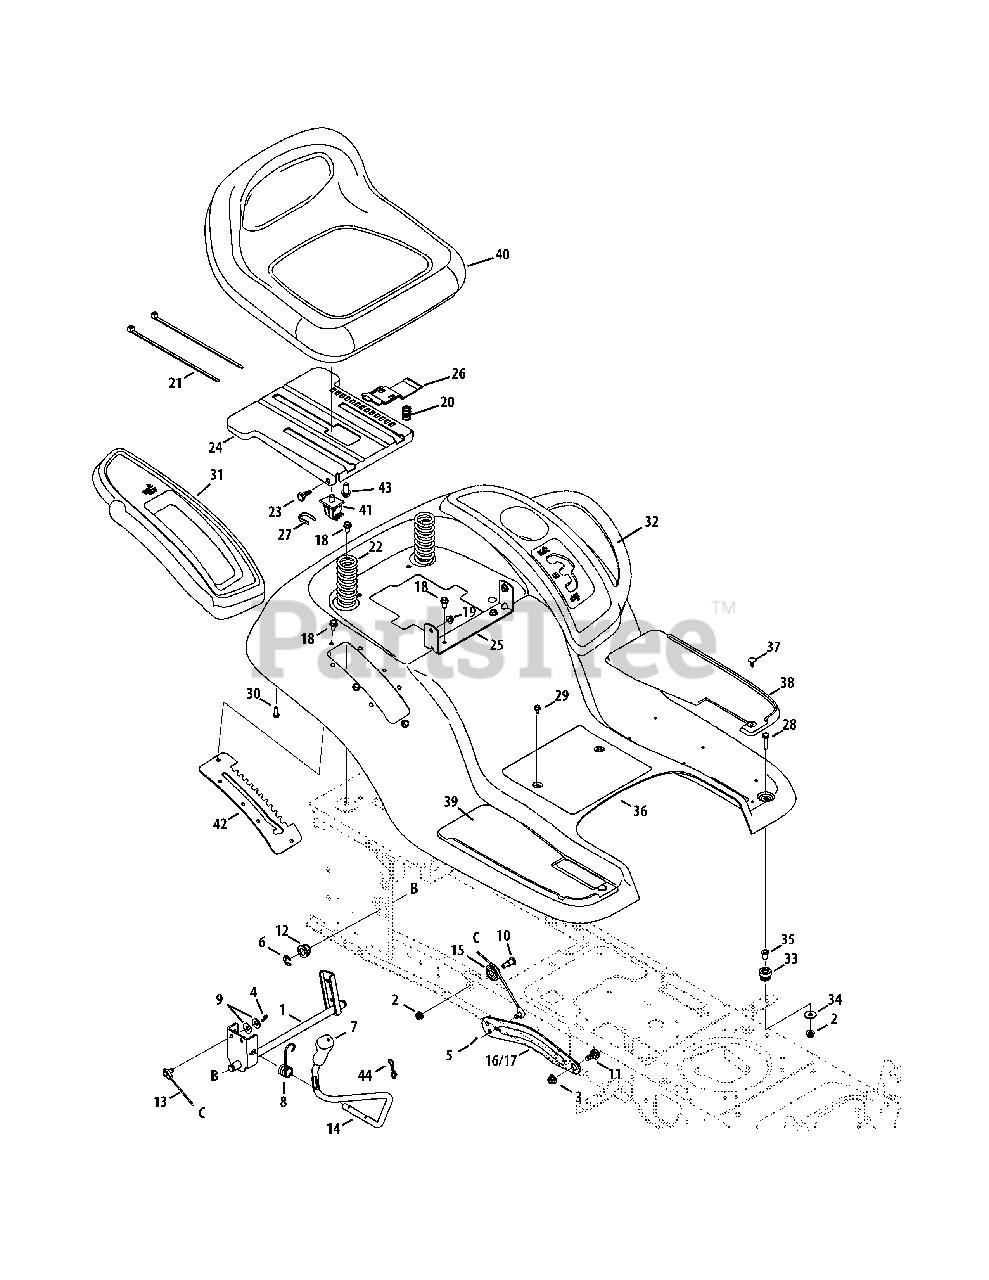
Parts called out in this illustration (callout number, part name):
1	Shaft Asm, Lift
2	Nut, Flange Lock, 5/16-18, Grf
3	Nut, Flange Lock, 3/8-16, Grf
4	Pin, Cotter, .072 Dia. x 1.13
5	Pin, Cotter, Bow-Tie 72
6	Ring, E Type, .625 Dia. Shaft
7	Grip, Handle, Cub, .50 ID
8	Spring, Torsion
9	Washer, Spring, .401 x .870 x .063
10	Screw, Shoulder, .437 x .470, 5/16-18
11	Bolt, Shoulder, .625, 3/8-16 (42")
12	Bearing, Hex Flange
13	Cable, Lift, 16.16
14	Handle, Lift,
15	Pulley, Roller, Cable
16	Arm, Lift, 42" Rt RH
17	Arm, Lift, 42" Rt LH
18	Screw, Self-tapping, 5/16-18, .750,
19	Nut, Flange Lock, 5/16-18, Gr5, Sd Lk
20	Spring, Comp, .68 x 1.065 x .055
21	Cable, Tie, 3/16 x .05 x 7.4
22	Spring, Comprs, 1.5 x 3.9 x .200
23	Screw, Shoulder, .437 x .268, 5/16-18
24	Bracket, Mounting, Seat
25	Bracket, Pivot, Seat
26	Lever, Seat Adjustment
27	Clip, Retaining, Switch
28	Hex Screw, 5/16-18, 1.25, Gr5, Std
29	Screw, Self-tapping, 1/4-20, 0.500
30	Screw, HL, 1/4-15, 0.750
31	Cover, Fender, RH
32	Cover, Fender, LH
33	Grommet, .4375 ID x .750
34	Washer, Flat .344 x 1.00 x .063
35	Spacer, Flange, .3125 x .4375 x .625
37	Clip, Ratchet, .250 Dia
38	Pad, Foot, LH
39	Pad, Foot, RH
40	Seat, Medium Back Cloth, Cub
41	Switch, Seat
42	Bracket, Lift, Manual PTO, 12 Pos
43	Hex Flange Bolt, 3/8/16, .875, Gr5
44	Pin, Cotter, Bow-Tie 72 (46" Decks)
